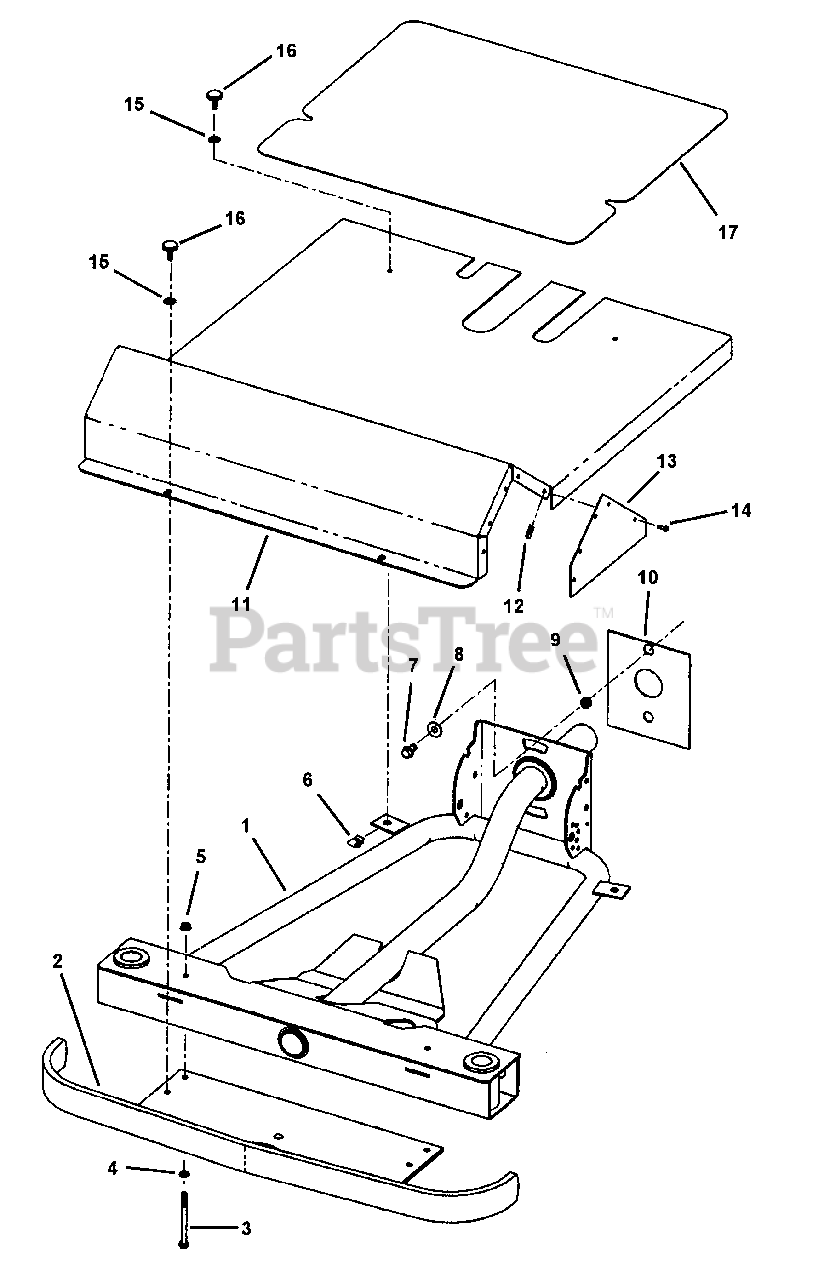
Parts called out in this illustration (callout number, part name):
1	FRAME, Front
2	BUMPER, Front
3	BOLT, 5/16-18 x 3-3/4"
4	WASHER, 5/16" Split Lock
5	NUT, 5/16-18 Hex Flange Lock, Grade 5
6	FASTENER, "U" Type 1/4-20
7	SCREW, 3/8-16 x 1" Hex Washer Face, Self-Tap
8	WASHER, 3/8" Flat
9	SPACER, Front Frame Pivot
10	PLATE, Front Frame Pivot
11	PAN, Floor
12	CLIP NUT, #10-24
13	PLATE, Floor End
14	SCREW, #10-24 x 1/2" Pan Head Machine
15	WASHER, 1/4" Internal/External Lock
17	FLOOR MAT
